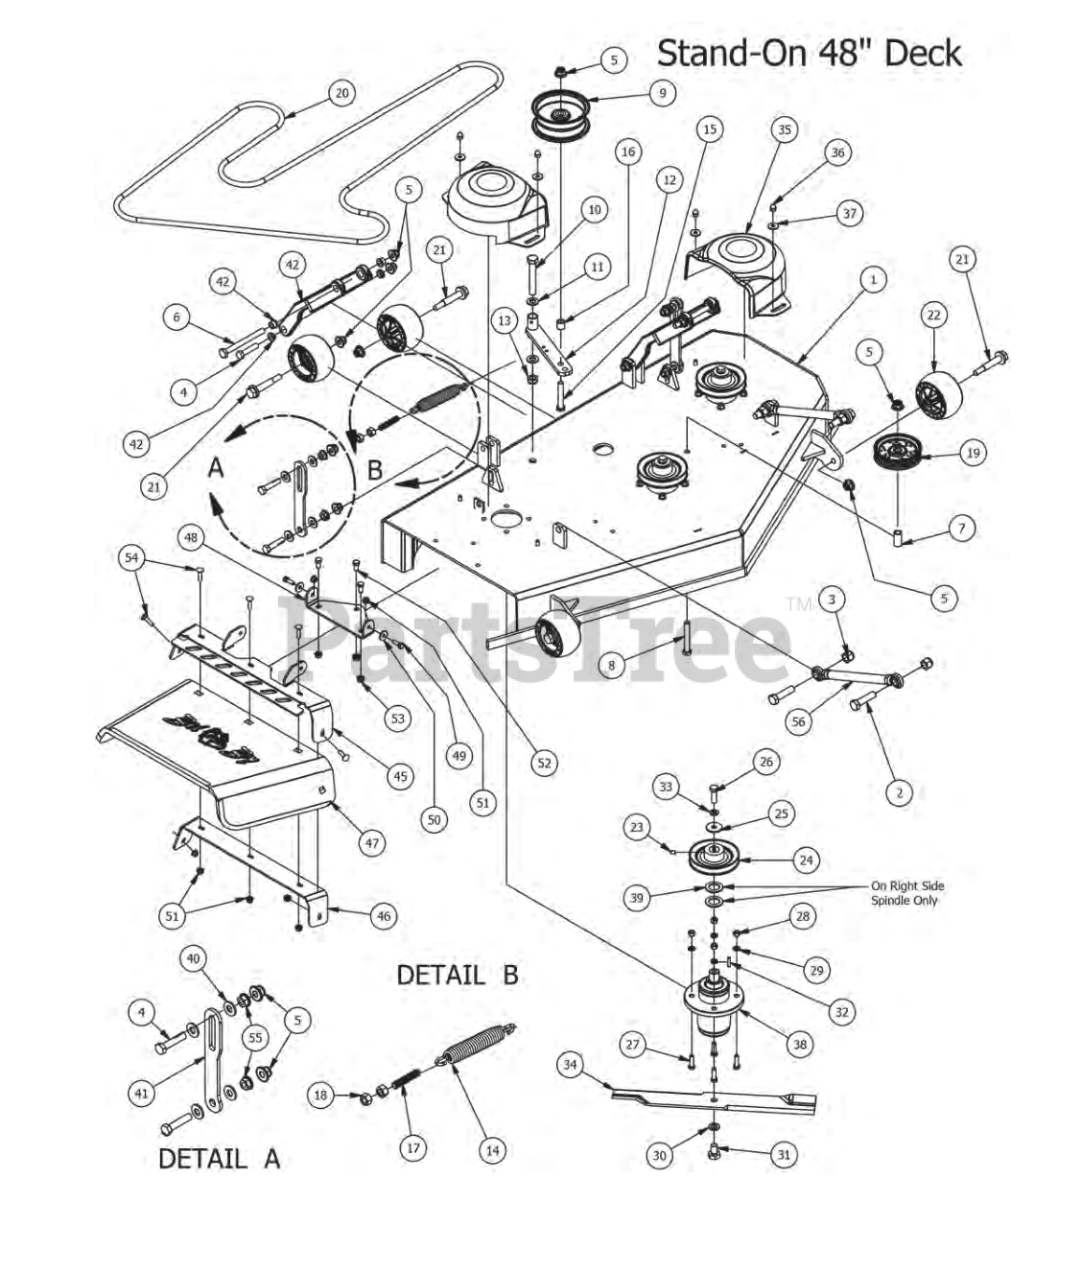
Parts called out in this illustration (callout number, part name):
1	48" 2015 Stand-On Deck (Welded Assembly)
2	5/8" x 2 1/2" Hex Bolt
3	5/8 Std NC Nylock Nut
4	1/2-13X 2-1/4 GR Hex Bolts
5	1/2-13 Nylon Flange Nut-Orange
6	1/2" x 5 1/2" Bolt
7	.502 ID X.75 OD X 1.500 Leng
8	1/2 x 3 1/2 Flange Bolt Grade 8
9	5 3/4" Deck Idler Pulley
10	5/8" x 4" Hex Bolt
11	.635 ID Plastic Washer
12	Deck Idler 2009 AOS
13	5/8" Nylock (1/2 Jam)
14	2009 Deck/Pump Idler Spring
15	1/2-13 x GR 5 Hex Bolt Zinc
16	3/4 OD x 1/2 ID x 3\4 Length
17	All Thread-pump Idler Tensioner
18	1/2" Hex Nut
19	4-3/4 Idler Pulley
20	B111 Belt 48" Stand-On
21	Deck Wheel Bolt
22	Anti-Scalp Rollers
23	5/16 Set Screw
24	5" Deck Pulley
25	1/2 Belleville Washer
26	1/2"-20 x 1 1/2- Grade 5 Fine Thread Bolt
27	3/8" x 1 1/4" Hex Bolt
28	3/8-16 Hex Nuts Zinc
29	3/8" Lock Washer
30	5/8" Lock Washer
31	5/8" x 1 1/2" Gr8 Hex Bolt (Fine)
32	1/4" x 1" Key
33	1/2" Lock Washer
34	Fusion Blade
35	Pulley Cover
36	Acorn nut-pulley Cover
37	.360 ID Plastic Washer-Black
38	OUTLAW SPINDLE ASSEMBLY
39	1 1/8" Flat Spacer
40	.505 Nylon Spacer
41	Longer deck hanger
42	Deck Arm Assembly
45	Upper Hanger
46	Discharge Lower Chute Bracket
47	Rubber Discharge Chute
48	Discharge Chute Hanger (deck mounted)
49	5/16" x 1" Bolt
50	.360 ID Plastic Washer
51	5/16" Nylon Flange Nut
52	3/8" x 3/4" Hex Bolt
53	3/8" Flange Nut
54	5/16" x 1 1/4" Carriage Bolt
55	1/2" Flange Nut
56	Turnbuckle (Top Link)
